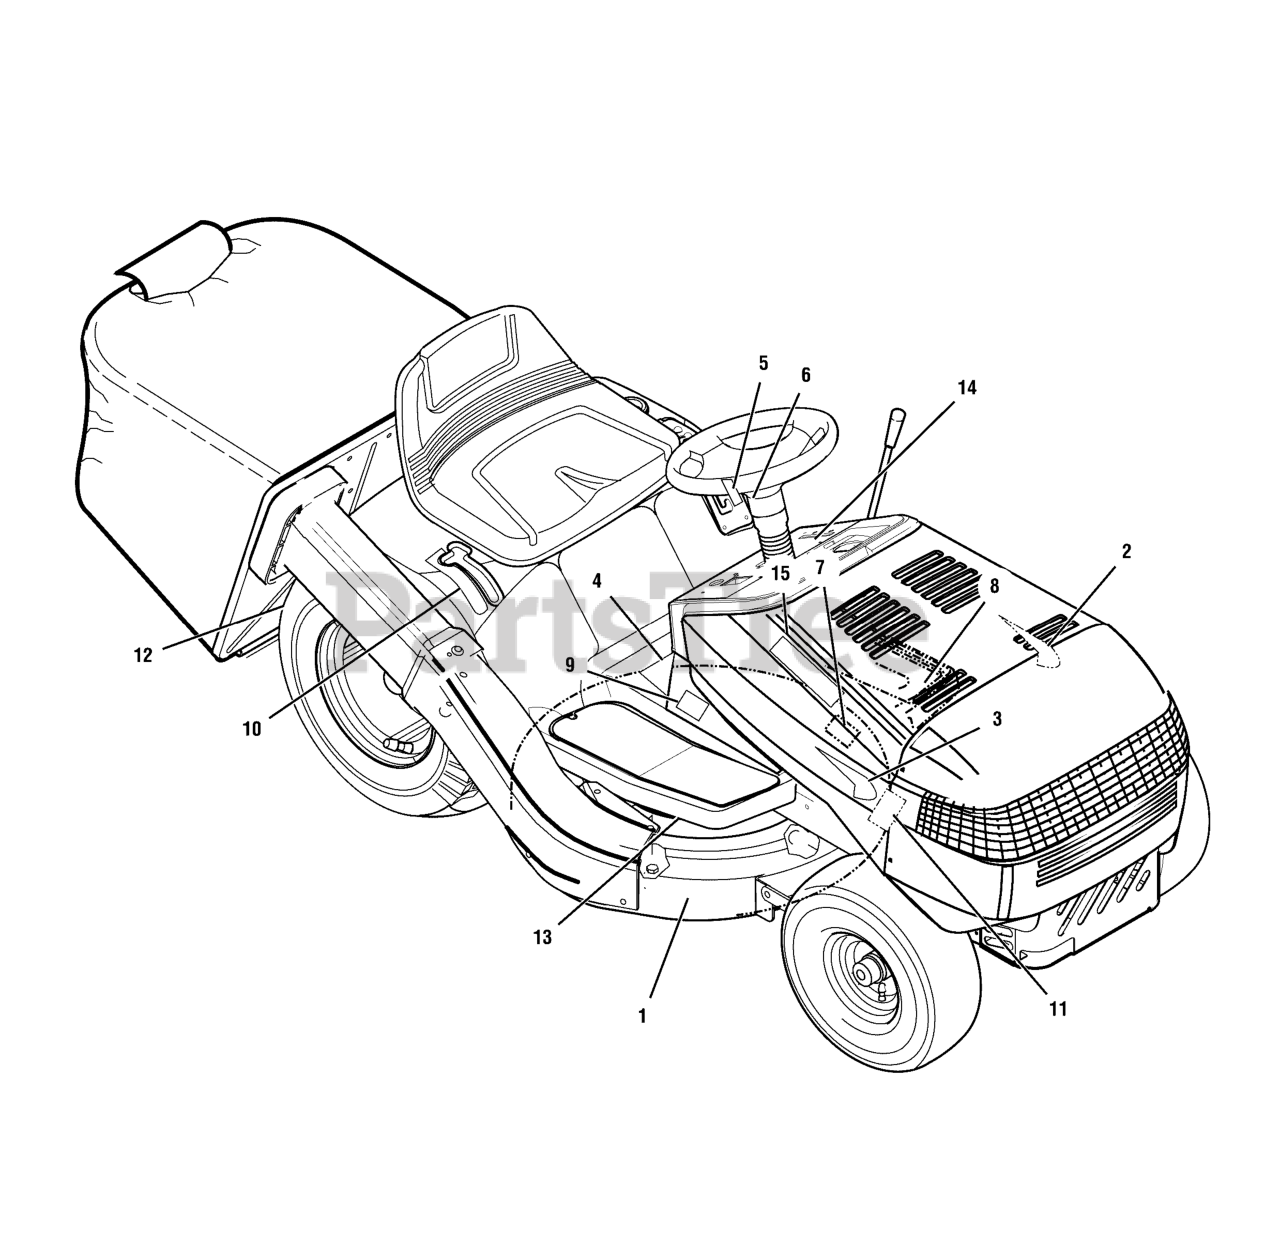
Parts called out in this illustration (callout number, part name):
1	DECAL, CUT FINGER SYMBOLS
2	DECAL, MASPORT 125/76 5SPD LH
3	DECAL, MASPORT 125/76 5SPD RH
4	DECAL, WARNING EXPORT
5	DECAL, 1/6 HGT ADJUST LIFT SMSD
6	DECAL, DECK LEVEL
7	DECAL, NO STEP EXPORT
8	DECAL, BRAKE/CLUTCH EXM
9	DECAL, B&S LOGO IC
10	DECAL, 5 SPEED
11	DECAL, HEAT SHIELD WARNING
12	DECAL, DRAWBAR WARNING MICT
13	DECAL, WARNING PINCH POINT
14	DECAL, DASH SYMBOLS 3510
15	DECAL, MASPORT LOGO
